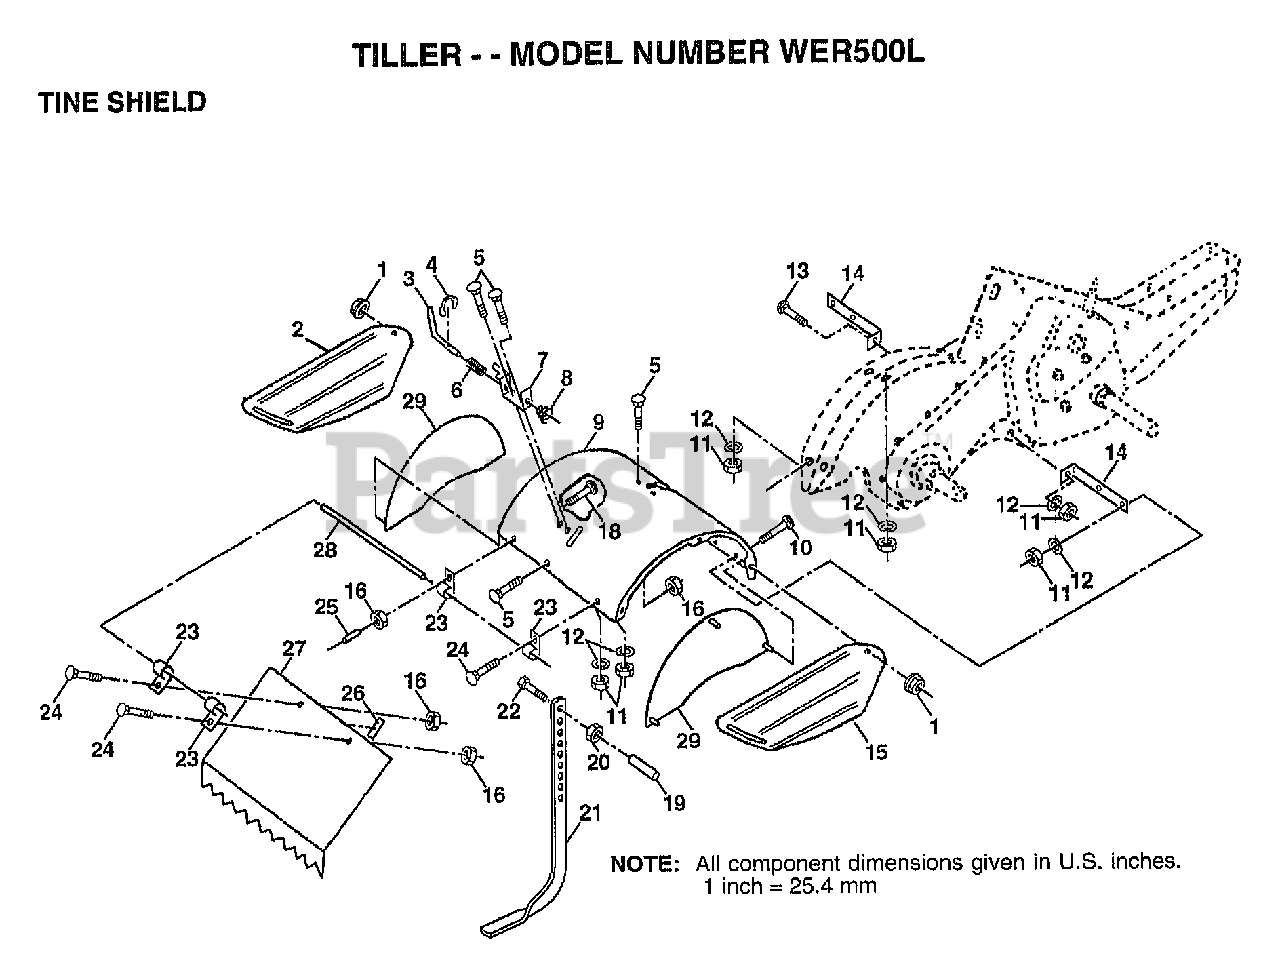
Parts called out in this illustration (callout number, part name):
1	NUT
2	SHIELD.SIDE.OUTER.LH
3	STAKE PIN TI
4	KLIP RING TI
5	BOLT
6	SPRING TI
7	LATCH BRACKET TI
8	SPRING CRT
9	SHIELD.TINE.PNT.
10	BOLT
11	NUT.HEX.5/16-18
12	LOCKWASHER
13	BOLT
14	BRKT SHIELD TINE
15	SHIELD.SIDE.OUTER.RH
16	NUT
18	BOLT
19	GRIP CRT
20	NUT.HEX.3/8-16UNC
22	BOLT
23	HINGE CRT
24	BOLT
25	VINYL CAP TI
26	PAD IDLER TI
27	SHIELD.LEVELING
28	PIN HINGE
29	SHIELD.SD.INNER
